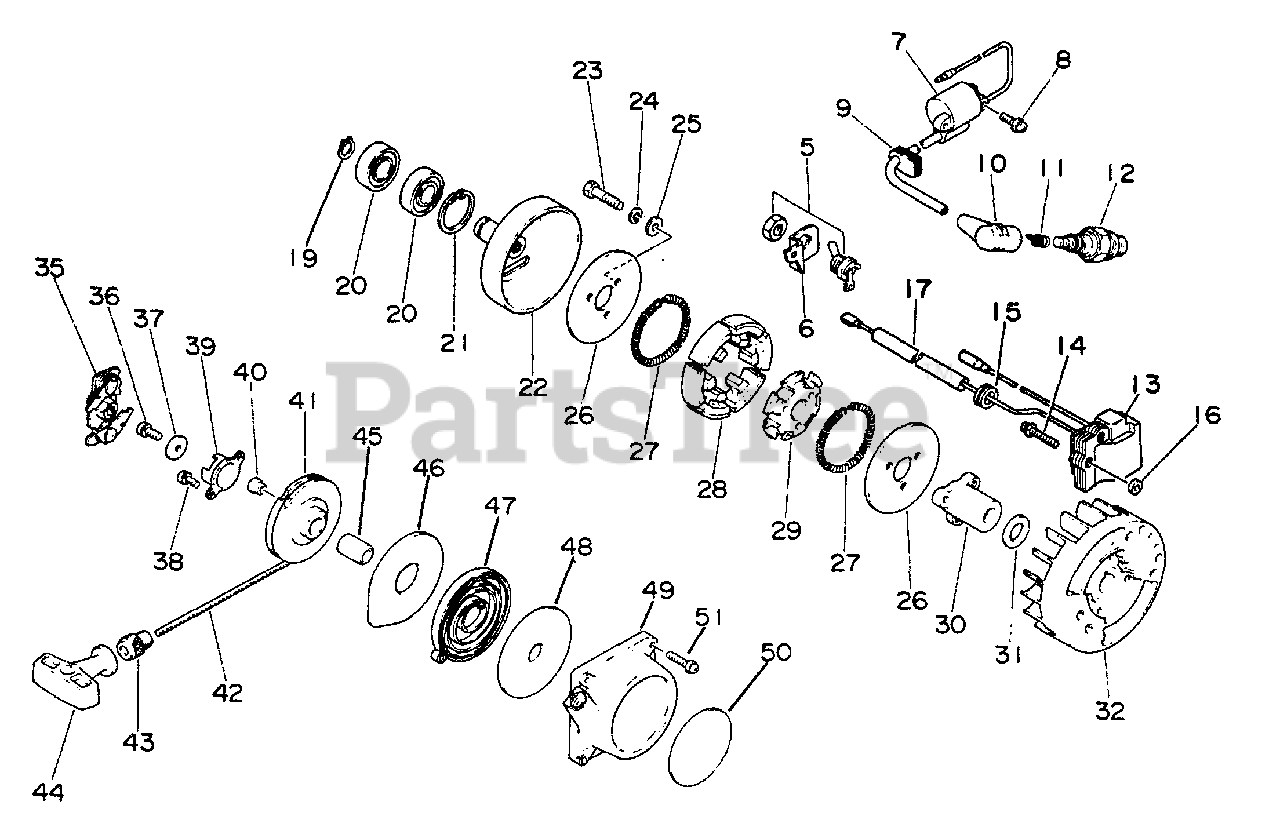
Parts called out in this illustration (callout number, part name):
5	IGNITION SWITCH KIT
6	BRACKET, SWITCH
7	COIL, IGNITION
8	SCREW - 4X14
10	CAP, SPARK PLUG
11	TERMINAL, SPARK PLUG CAP
12	SPARK PLUG -- BPM-7A
13	COIL, IGNITION
14	SCREW - 4X22
17	TUBE
19	RING, RETAINING - 15
20	BEARING, BALL - 6203
21	RING, RETAINING - 35
22	DRUM, CLUTCH
23	BOLT - 5X25
24	LOCKWASHER - 5
25	WASHER - 5
26	PLATE, CLUTCH
27	SPRING, CLUTCH
28	SHOE, CLUTCH
29	HUB, CLUTCH
30	ADAPTOR
31	WASHER
32	FLYWHEEL
35	STARTER PAWL ASSY
36	SCREW - 5X10
37	WASHER - 5
38	SCREW - 4X8
39	CATCHER, PAWL
40	RETAINER, ROPE
41	REEL, ROPE
42	ROPE, STARTER - 3.5X850
43	GUIDE, ROPE
44	GRIP, STARTER
46	PLATE, STARTER
47	SPRING, REWIND
48	PLATE, STARTER
49	CASE, STARTER
50	LABEL - ECHO
51	SCREW - 4X20
